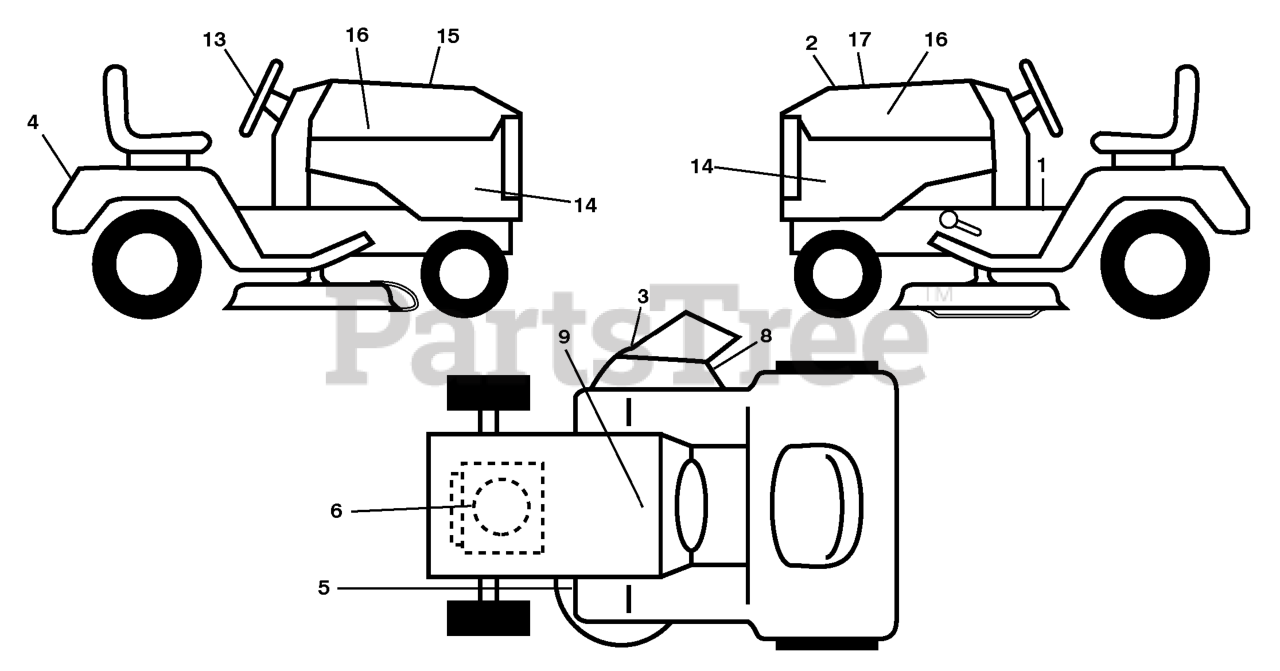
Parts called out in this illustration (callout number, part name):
1	DECAL.FENDER.OPER.TEX.
2	DECAL.HOOD.TOP.INSERT.
3	DECAL.WARN.KEEP.HAND.AWAY
4	DECAL.FENDER
5	DECAL CLUTCH/BRAKE
6	DECAL ENGINE HP
8	DECAL.MOWER.SCH.48/54
9	DECAL BTRY SYMBOLS
13	DECAL.WHEEL.STRG.LGN.H
14	DECAL, PANEL SIDE
15	DECAL HOOD CUST. RESP.
16	DECAL.HOOD.NAMELOGO.HUSQ
17	DECAL.RPL.BS.22INTK/HY/48E.TLT
17	DECAL.BYPASS.FENDER.CRD.LT.YT
